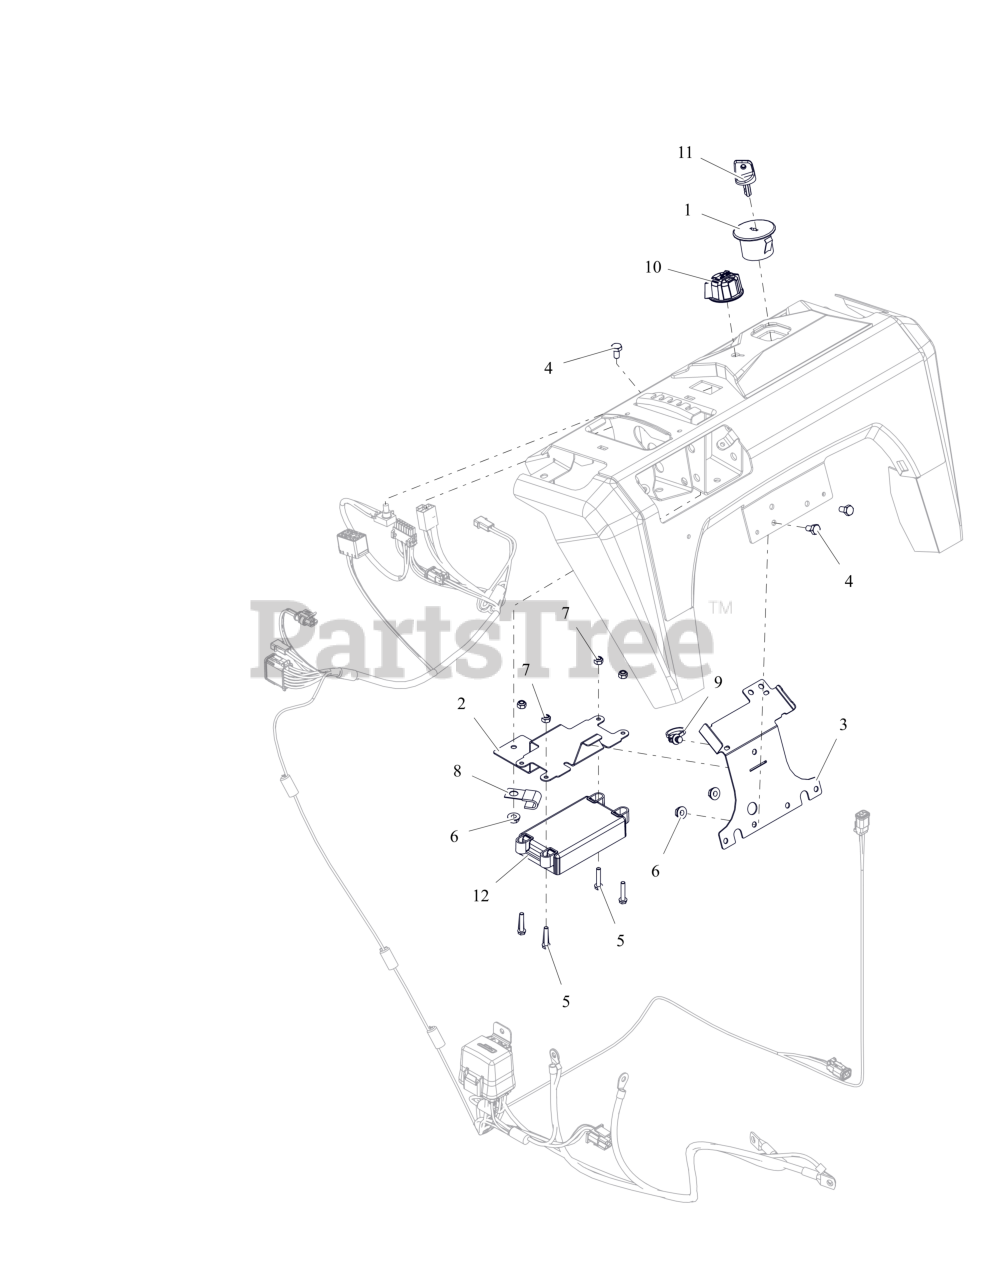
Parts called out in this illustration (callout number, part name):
1	KEYSWITCH-IGNITION 3 POS
2	BRACKET, ENGINE EFI-LCT LOWER
3	BRACKET, ENGINE EFI-LCT UPPER
4	BLT,HEX .25-20X.50 G5 ZCC
5	BLT, HWH #10-24X1.00 ZCC
6	NUT-LK-TOP-FLG .250-20 GF ZCC
7	NUT-LK-NYL #10-24 G2 ZCC
8	J-CLAMP
9	CABLE TIE W/ TREE (.25 HOLE)
10	KNOB- CONTROL EFI
11	KEY- IGNITION
12	ECU, AX420 12V EFI
